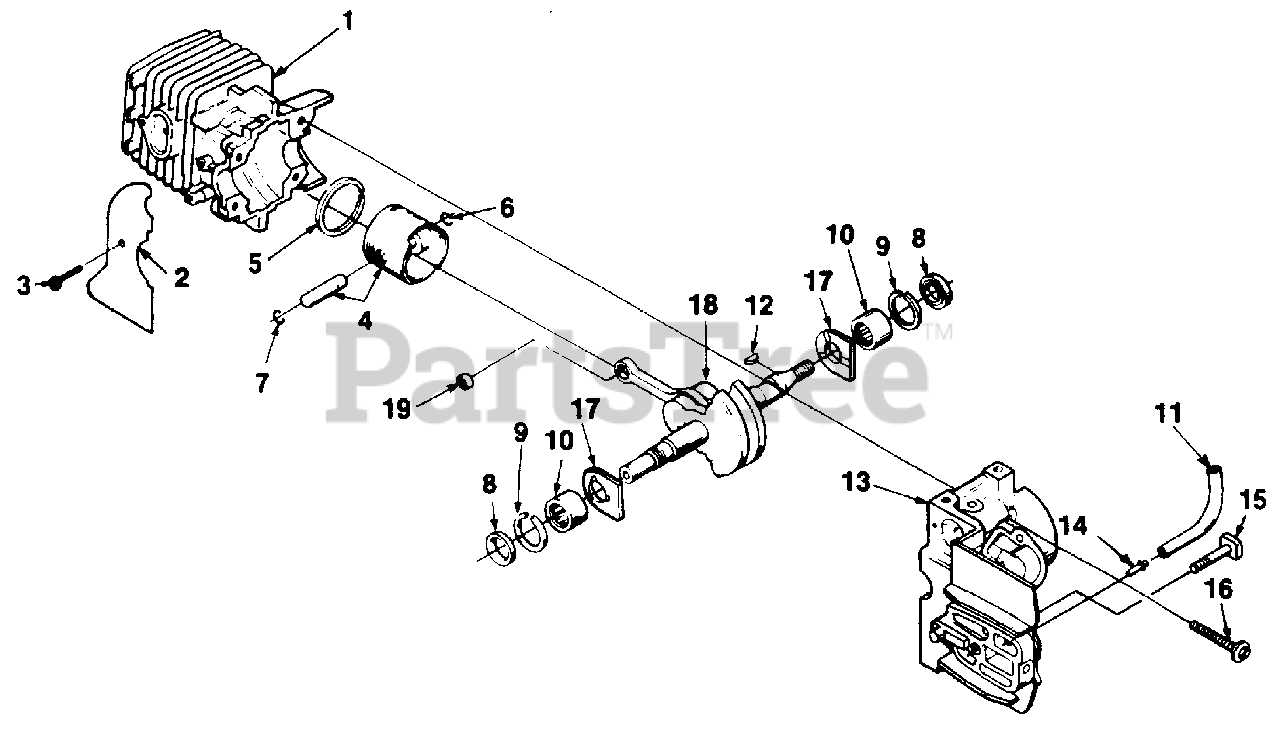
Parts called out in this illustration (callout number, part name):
1	CYLINDER (Super 2 Only)
2	SHIELD- Sawdust
3	SCREW- Tapping (#6-32 x 5/16")
4	PISTON & PIN ASSY (Super 2 Only)
5	RING- Piston
6	RING- Retaining
7	RING- Retaining
8	SEAL
9	SPACER
10	BEARING- Needle
11	TUBING- Rubber (Oil Line)
13	CRANKCASE ASSY.
14	FITTING
15	BOLT- Guide bar thd. forming
16	SCREW- Torx pan hd. (10-24 x 1 1/8")
17	WASHER- Thrust
18	CRANKSHAFT ASSY.
19	BEARING
